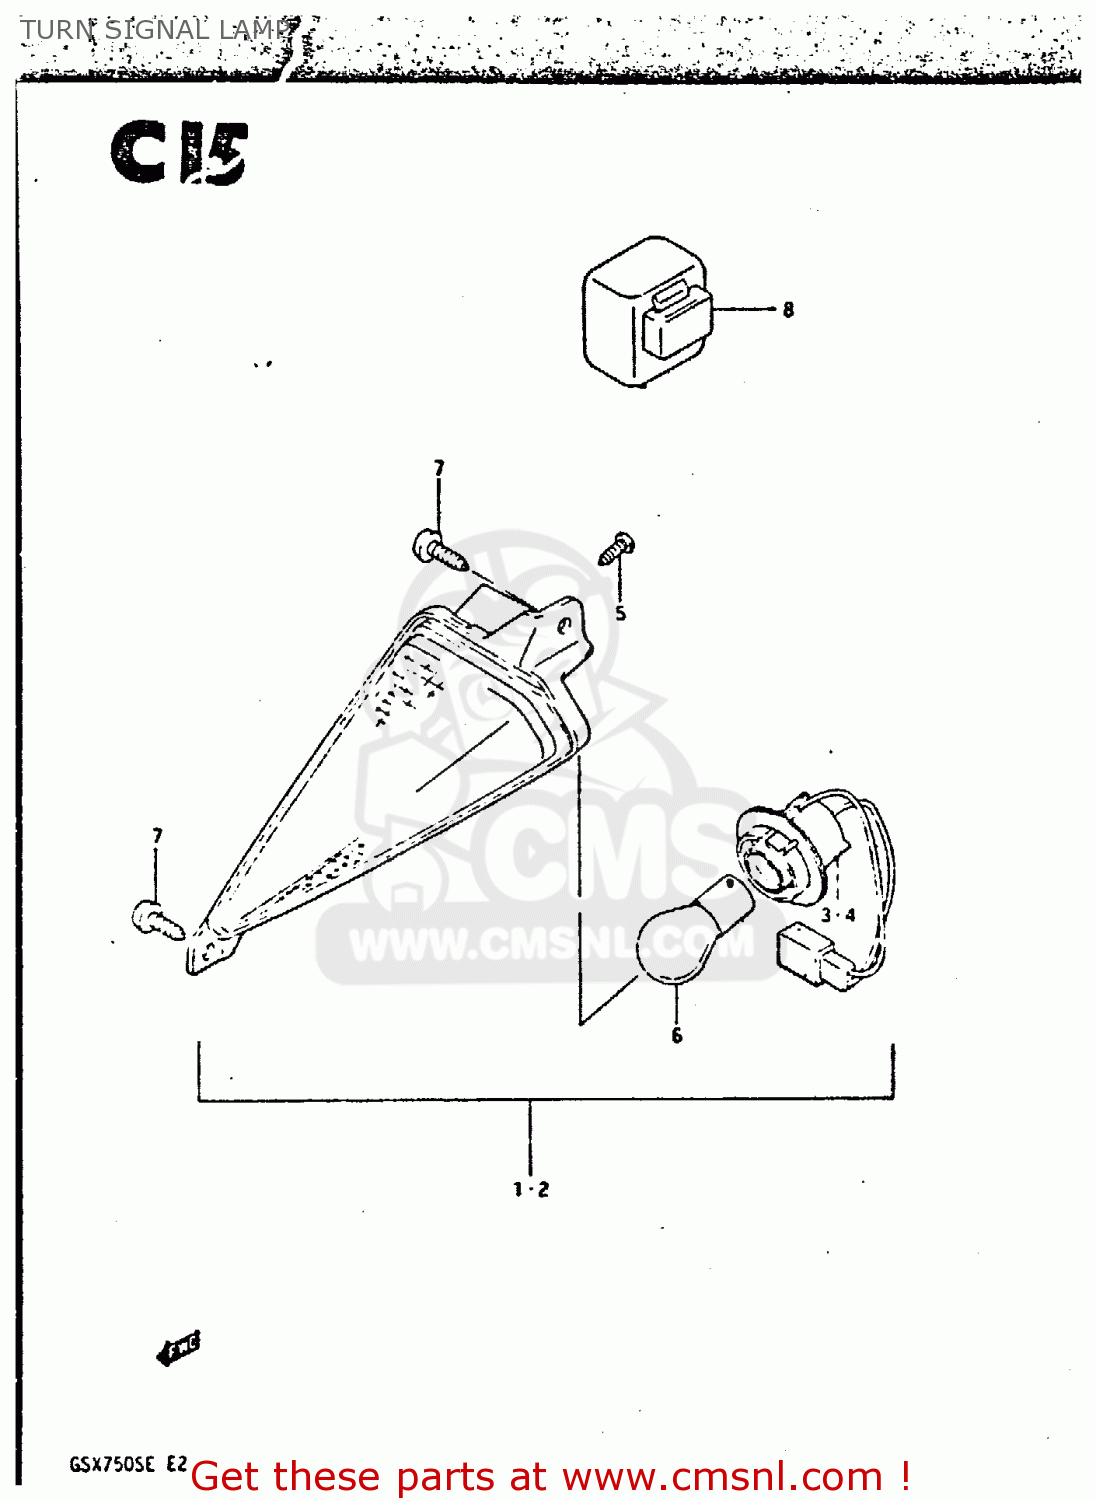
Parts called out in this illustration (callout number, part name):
1	LAMP ASSY, FRONT TURN SIGNAL RH
2	LAMP ASSY, FRONT TURN SIGNAL LH
3	SOCKET, RH
4	SOCKET, LH
5	SCREW
6	BULB(12V23W,STANLEY,A4577A)
7	SCREW
8	RELAY ASSEMBLY,TURN SIGNAL
